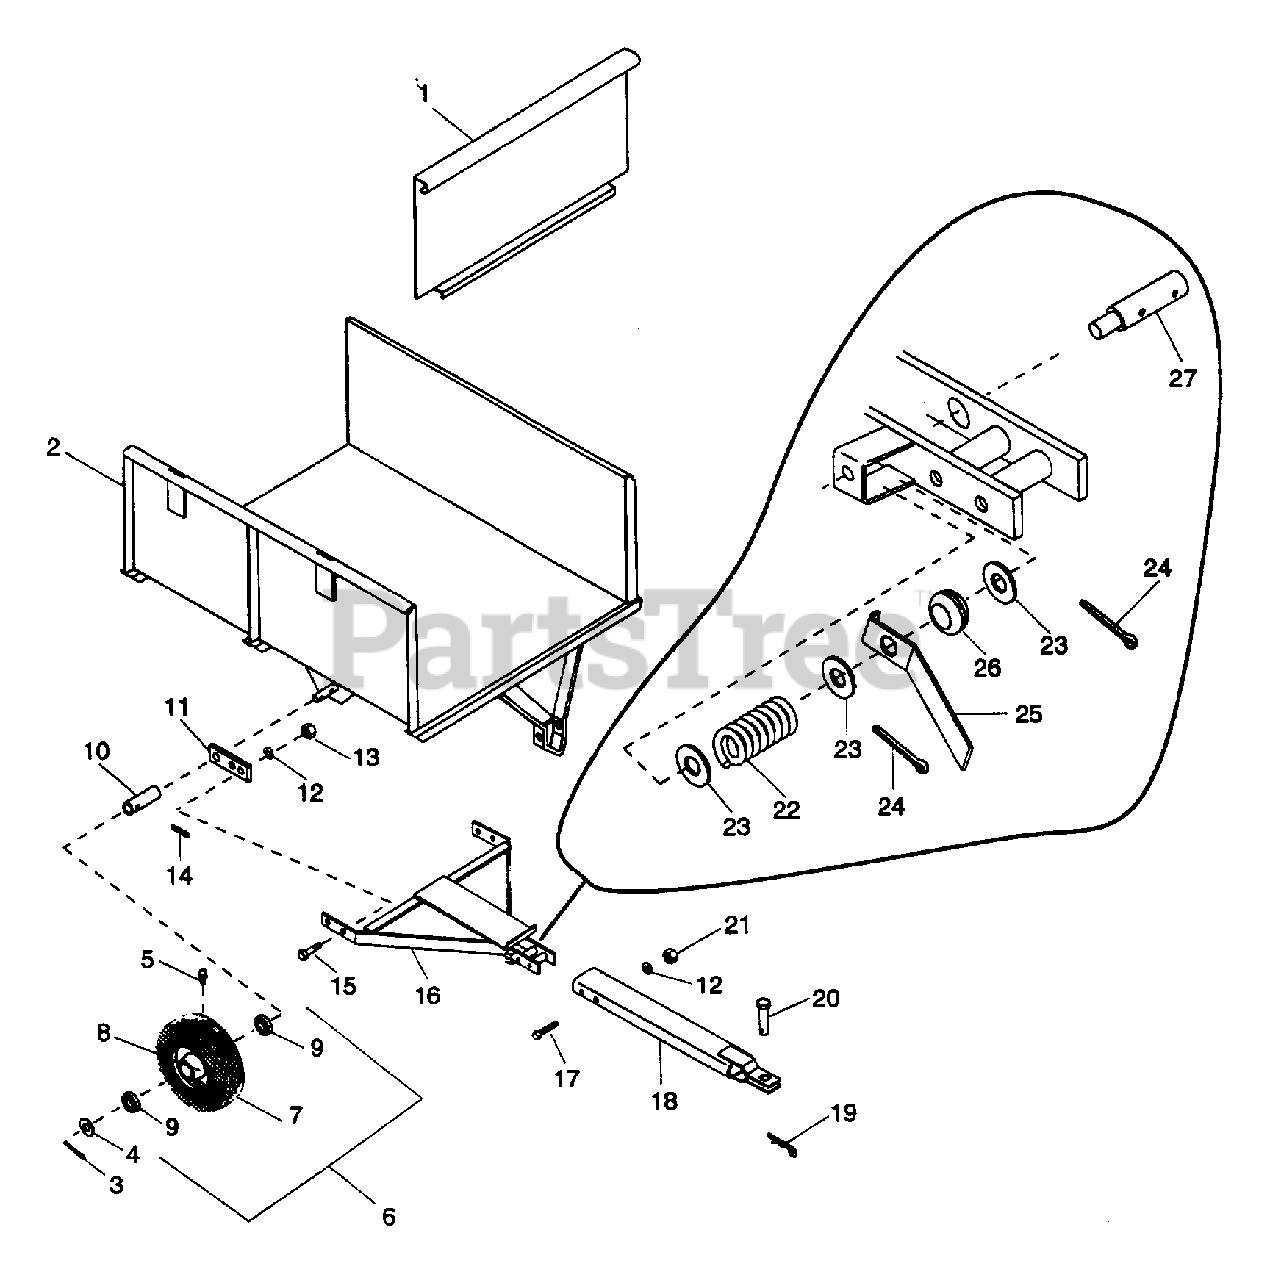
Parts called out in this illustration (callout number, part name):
1	GATE WELDMENT
2	BOX WELDMENT
3	PIN-COTR .18X1.50 PL
4	WSHR-FL-STL 1.015X1.500X.125
5	FTG-LUBE .25-28X.256 YWZC
6	TIRE 8X1.75
7	TIRE 16X6.50-8 2 PLY
9	BRG-BALL 1.0X2.0X.55
10	SHAFT COLLAR
12	WSHR-LK .500X.151 HVY PL
13	NUT .50-13 PL
14	PIN-ROLL .250X1.75
15	BLT-HEX .50-13X1.25 PL GR2
16	TONGUE WELDMENT
17	BLT-HEX .50-13X3.00 PL GR2
18	POLE WELDMENT
19	PIN-HAIR INT .14X.4X2.75
20	HITCH PIN
21	NUT-JAM .50-13 PL
22	SG-COMP .62X.68X1.75
23	WSHR-FL-STL .505X1.000X.062
24	PIN-COTR .12X1.0 PL
26	GROMMET .50IDX.812OD
